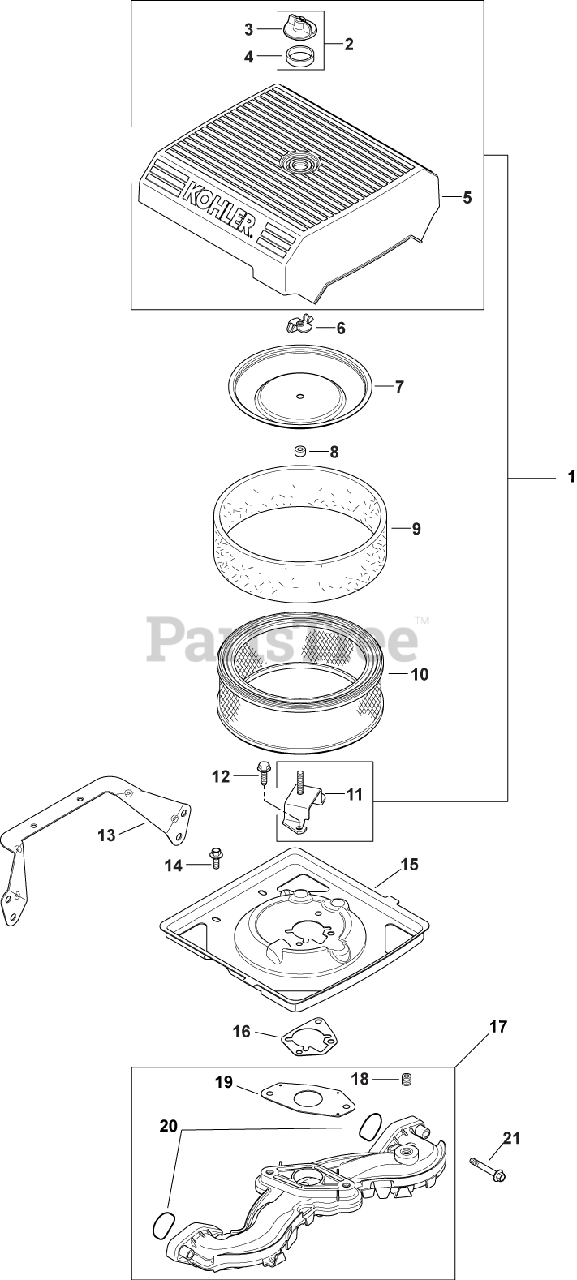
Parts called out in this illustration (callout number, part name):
1	KIT, AIR CLEANER COVER
2	KIT, KNOB W/SEAL
3	KNOB, COVER
5	COVER, AIR CLEANER
6	NUT, WING
7	COVER, INNER AIR CLEANER
8	SEAL, INNER AIR CLEANER
9	ELEMENT, PRECLEANER (LOW)
10	ELEMENT, AIR CLEANER - Also available Retail Packaged 47 883 03-S1 Air Filter Kit
11	BRACKET,AIR CLEANERBASE-USE 24 126 206-S
12	SCREW, FLG THD FRM M6X1.0X16
13	BRACKET, AIR CLEANER BASE
14	SCREW, FLG THD FRM M5X.8X10
15	BASE, AIR CLEANER-USE 24 094 84-S
16	GASKET, AIR CLEANER BASE
17	KIT, INTAKE MANIFOLD
18	PLUG, CTSK PIPE 1/8"
19	GASKET, CARBURETOR
20	O-RING, INTAKE PORT
21	SCREW, FLG M6X1.0X40
